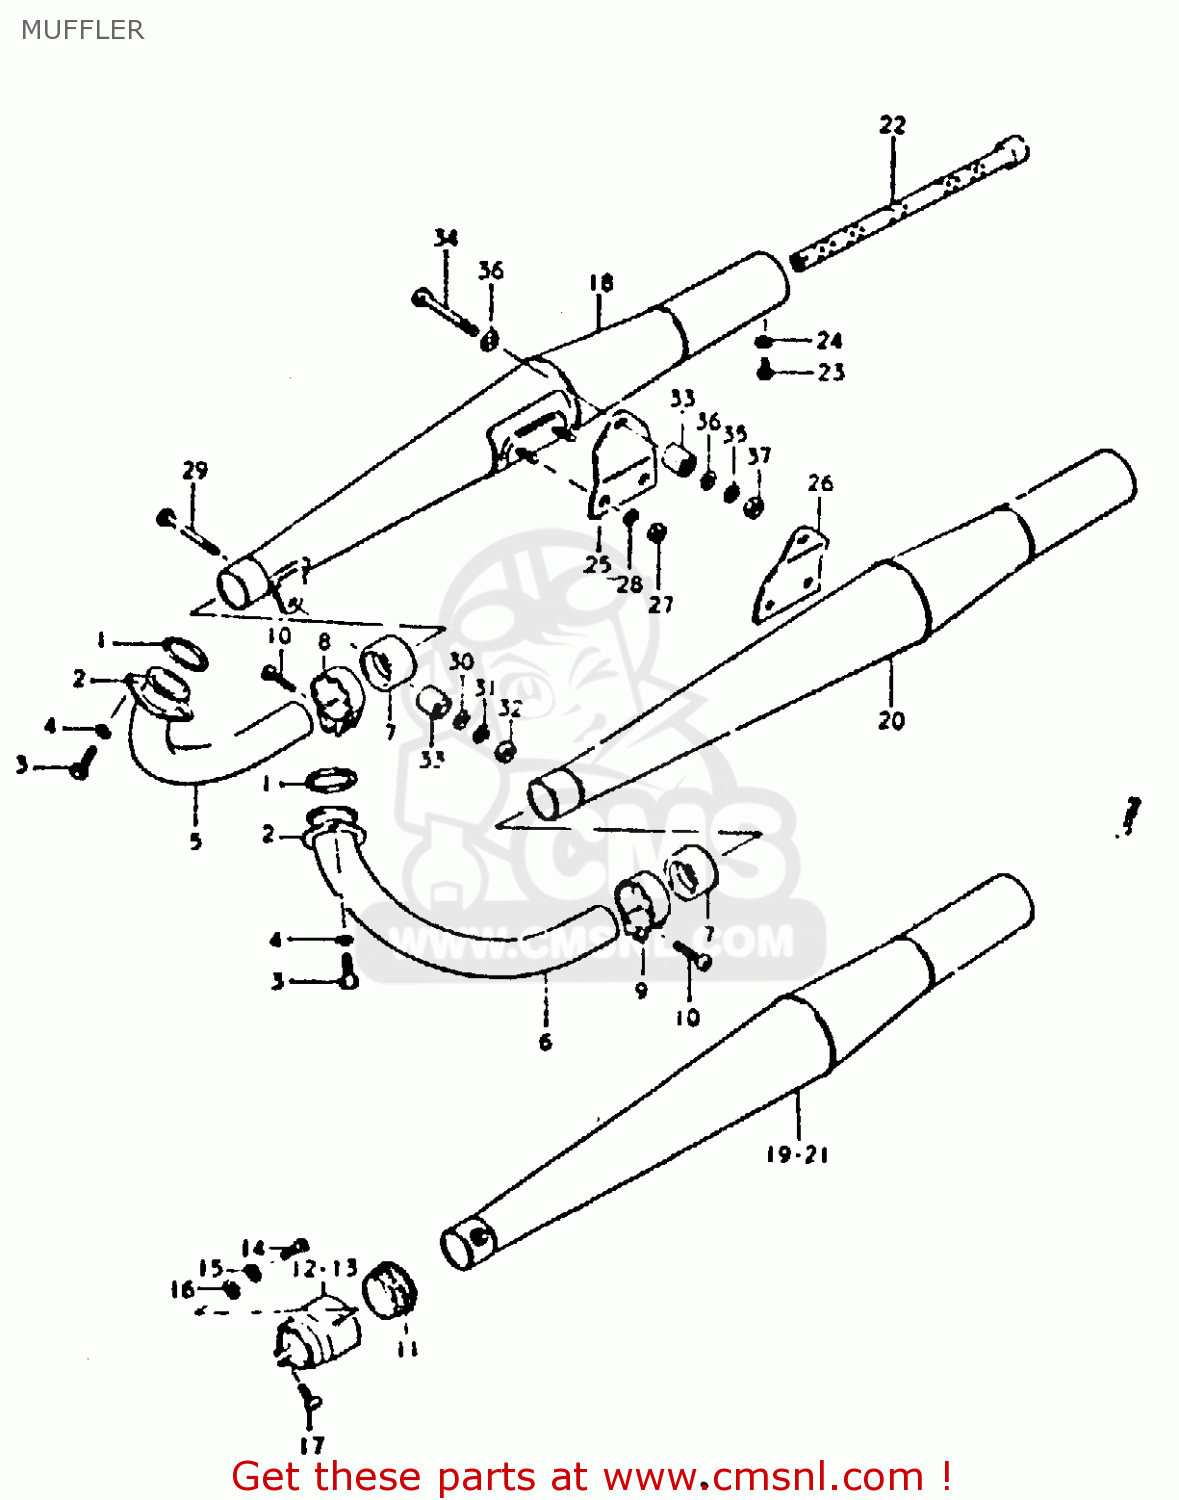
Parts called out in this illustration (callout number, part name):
1	GASKET,EXHAUST PIPE (NAS)
2	CLAMP
3	BOLT
4	LOCK WASHER
5	PIPE,EXHAUST,R
6	PIPE, EXHAUST LH
7	CONNECTOR,MUFFLER
8	CLAMP,R
9	CLAMP, LH
10	SCREW
11	CONNECTOR,MUFFLER
12	COVER, MUFFLER RH
13	COVER,MUFFLER,L
14	SCREW
15	LOCK WASHER
16	WASHER
17	SCREW 5X20
18	MUFFLER ASSY, RH
19	MUFFLER,R
20	MUFFLER ASSY, LH
21	MUFFLER,L
22	PIPE,BAFFLE,L
23	BOLT(5X8)
24	LOCK WASHER
25	BRACKET, RH
26	BRACKET, LH
27	NUT
28	LOCK WASHER
29	BOLT 10X55
30	WASHER
31	LOCK WASHER
32	NUT
33	BUSH
34	BOLT 10X55
35	LOCK WASHER
36	WASHER
37	NUT
